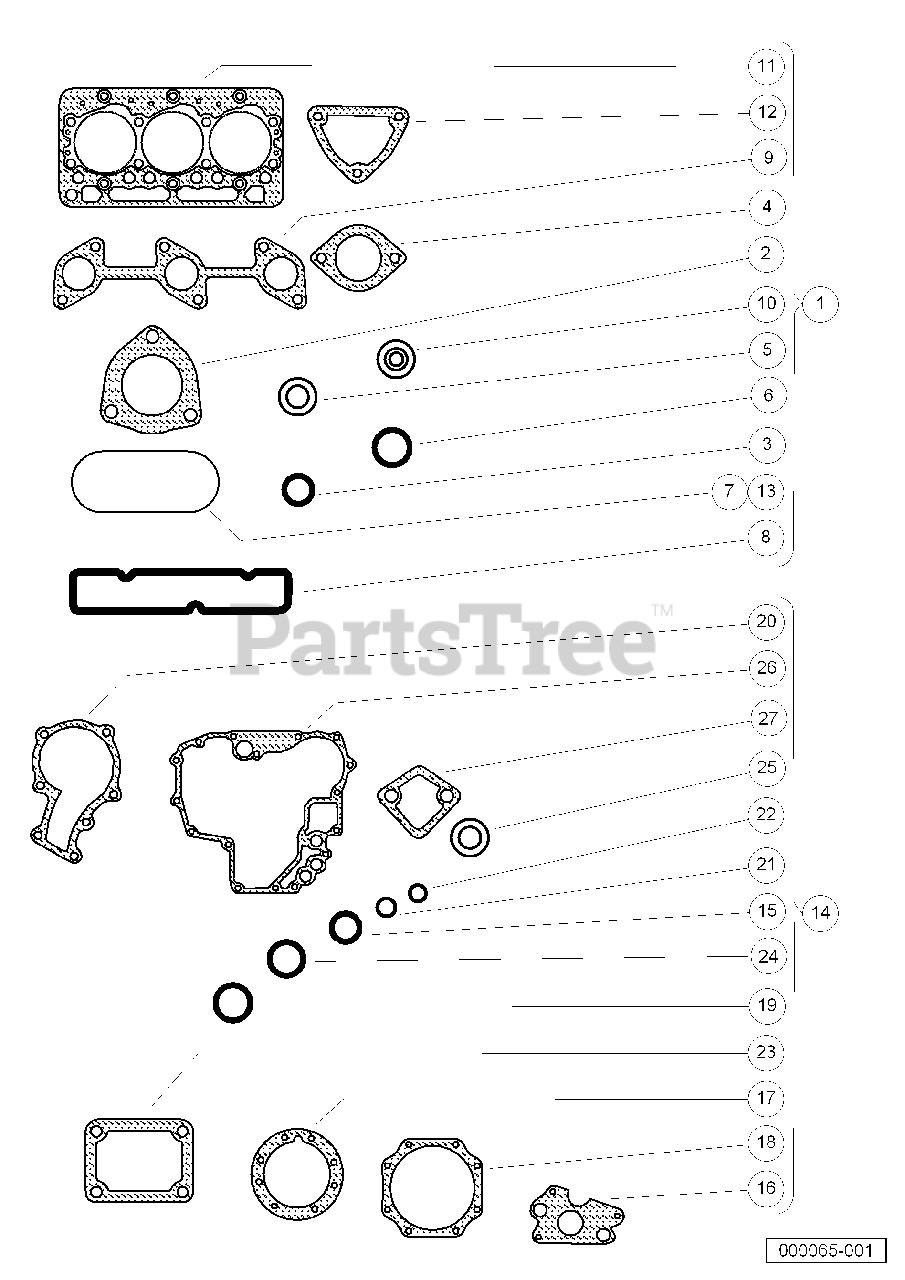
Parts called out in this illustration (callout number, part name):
1	Kit, Gasket Upper, D722
2	Gasket, Exhaust Diesel
3	O Ring, 8 X 7
4	Gasket, Thermostat
5	Gasket, 6 X 10
6	O Ring, 30 X 36
7	Gasket, Head Cover
8	Gasket, Intake Manifold
9	Gasket, Ex-manifold
10	Seal, Valve Stem
11	Gasket, Cylinder Head
12	Gasket, Water Flange
13	Gasket, Cylinder Head Cover
14	Kit, Gasket Lower, D722
15	O Ring, 18 X 13
16	Gasket, Oil Pump
17	Gasket, Bearing Case
18	Gasket, Cover
19	O Ring, 23 X 26
20	Gasket, Water Pump, D722
21	O Ring, 19 X 16
22	O Ring, 9 X 7
23	Gasket, Control Plate
24	O Ring, 20 X 17
25	Gasket, Idle Apparatus, Rear
26	Gasket, Gearcase, D722
27	Gasket, Fuel Pump, D722
